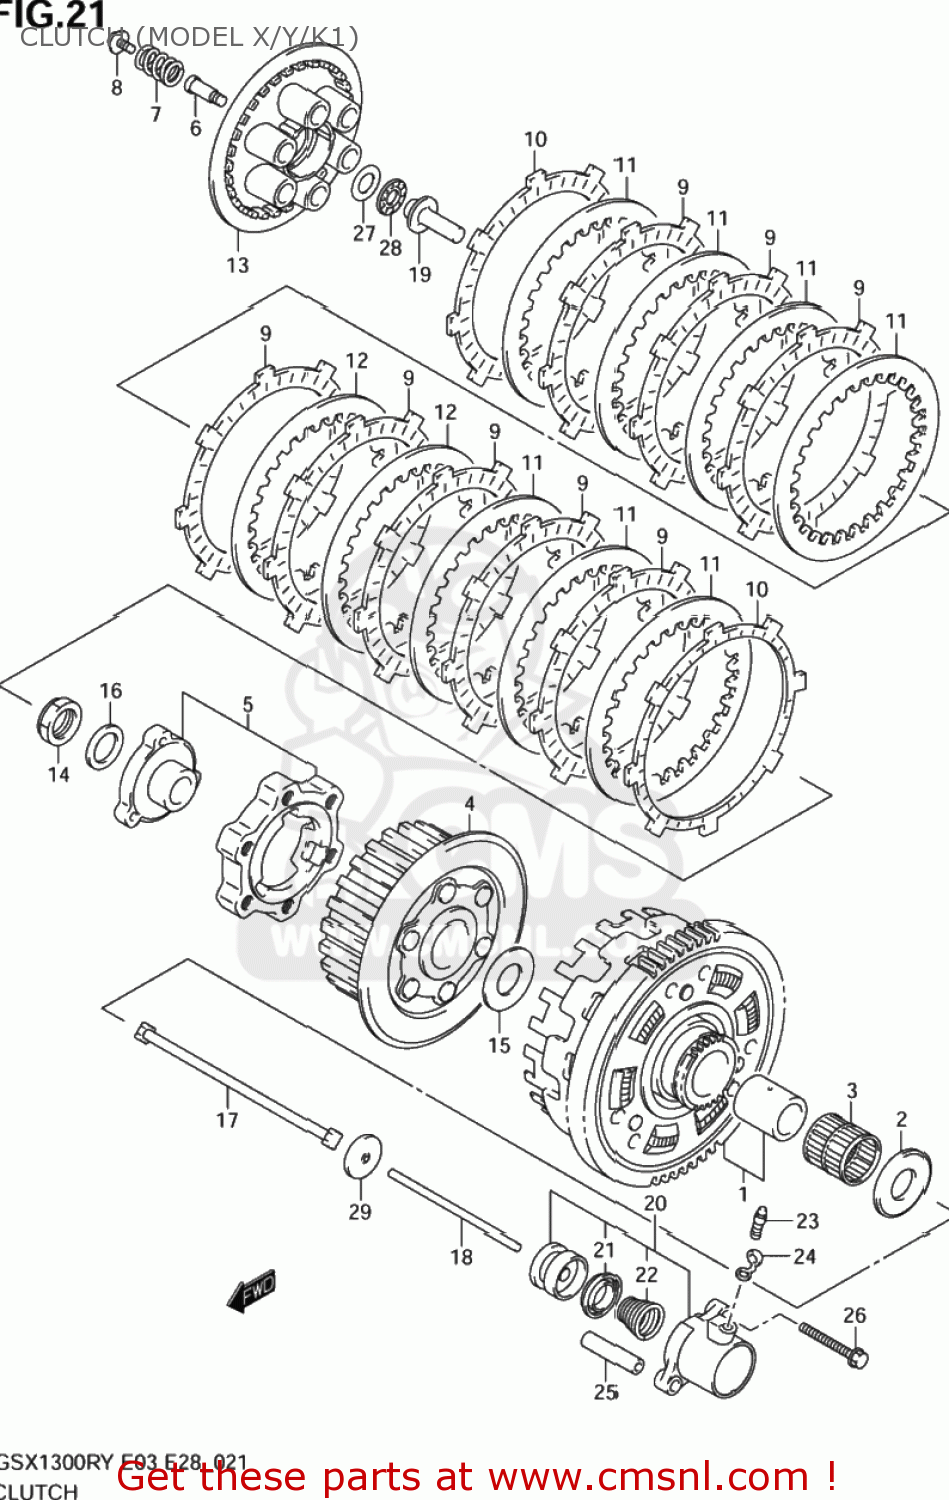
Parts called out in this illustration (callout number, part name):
1	GEAR ASSY,PRI DRIVEN
2	WASHER(25X54X2.5)
3	BEARING(35X40X39.8)
4	HUB,CLUTCH SLEEVE
5	CAM SET,CLUTCH
6	BOLT,SPRING SUPPORT
7	SPRING,CLUTCH
8	BOLT,CLUTCH SPRING
9	PLATE,CLUTCH DRIVE NO.1 (NAS)
10	PLATE,CLUTCH DRIVE NO.2 (NAS)
11	PLATE,CLUTCH DRIVEN NO.1(T:2.0 (NAS)
12	PLATE,CLUTCH DRIVEN NO.2(T:2.3 (NAS)
13	DISC,CLUTCH PRESSURE
14	NUT
15	WASHER(25X50X2.5)
16	WASHER
17	ROD,CLUTCH
18	ROD,CLUTCH PUSH,L
19	PIECE,CLUTCH PUSH
20	CYLINDER,CLUTCH RELEASE
21	CUP,CLUTCH CYLINDER
22	SPRING,CLUTCH CYLINDER
23	BLEEDER
24	CAP,BLEEDER
25	PIN
26	BOLT,CL.COVER
27	WASHER(15.5X28X1)
28	BEARING(15X28X2)
29	SEAL,OIL(6X34X5.5)
